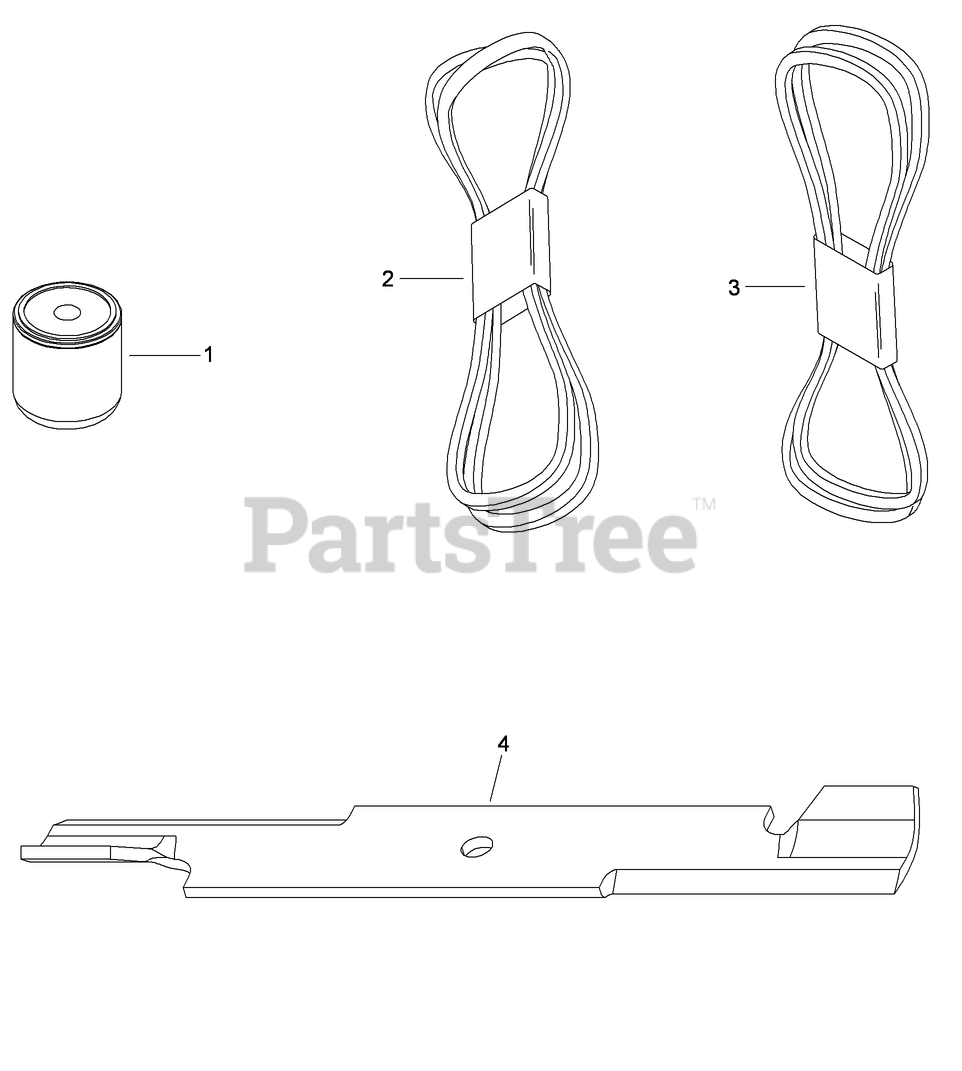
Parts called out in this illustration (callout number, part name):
1	FILTER-OIL, HYD
3	BELT-V
4	BLADE-18IN, HI FLOW
